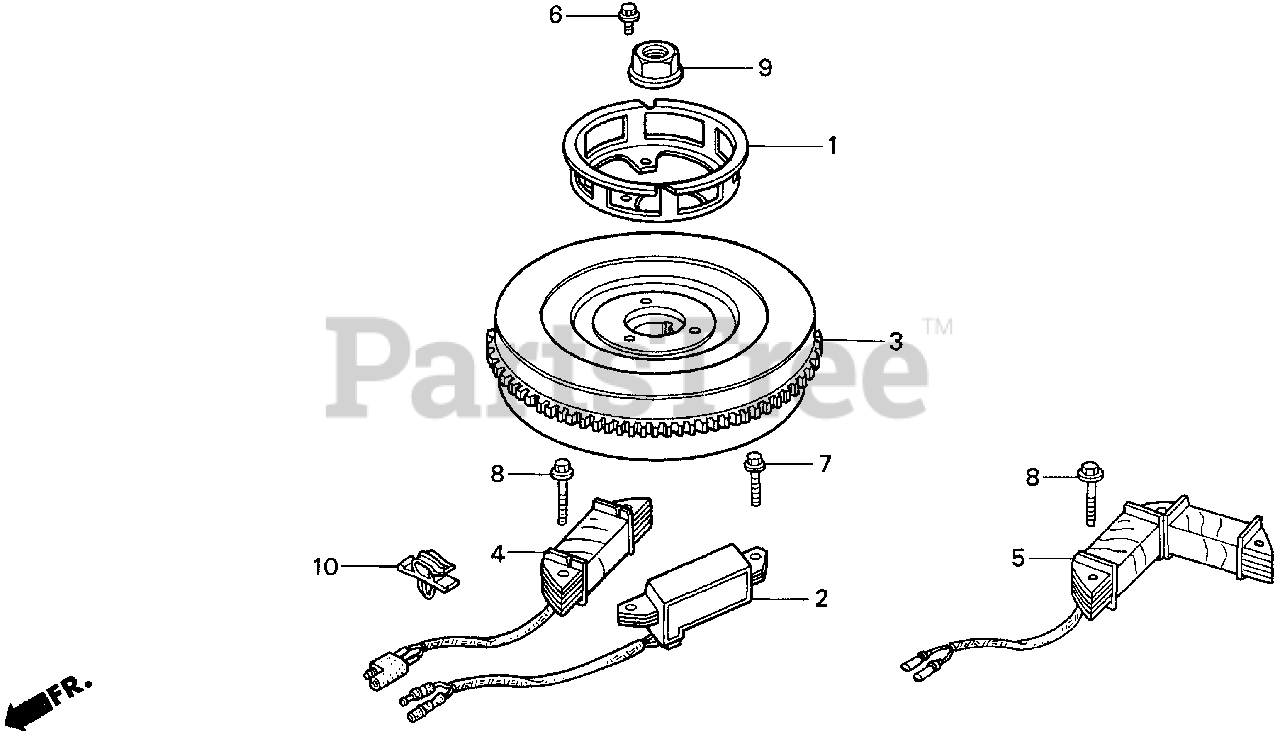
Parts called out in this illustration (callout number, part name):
1	PULLEY, STARTER
2	COIL ASSY., EXCITER
3	FLYWHEEL (SEL)
4	COIL ASSY., CHARGE (12V-6A)
6	BOLT, FLANGE (6X12)
7	BOLT, FLANGE (6X25)
8	BOLT, FLANGE (6X32)
9	NUT, SPECIAL (16MM)
10	CLIP, CORD
